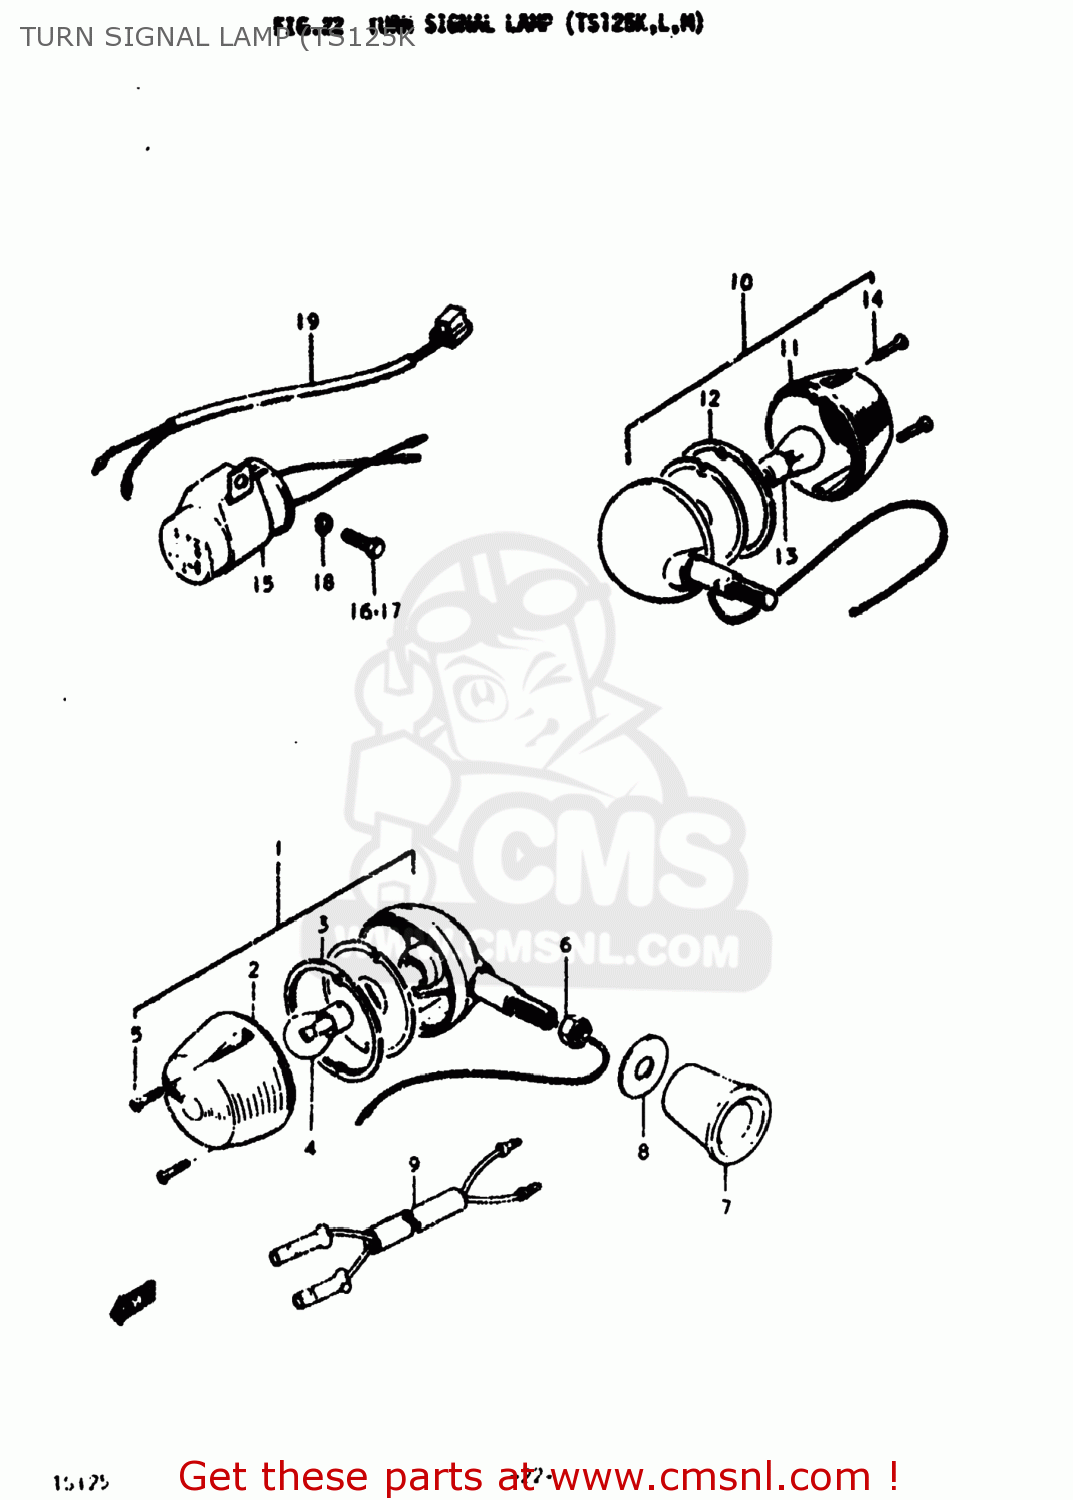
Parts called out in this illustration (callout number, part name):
1	LAMP ASSEMBLY,FRONT TURN SIGNAL
2	LENS,TURNSIGNAL
3	GASKET,TURNSIGNAL LENS (NAS)
4	BULB(6V17W,STANLEY,A4513A)
5	SCREW
6	NUT
7	COVER,FRONT TURN SIGNAL BRACKET
8	WASHER
9	WIRE,REAR TURN SIGNAL,LEFT
10	LAMP ASSEMBLY,REAR TURN SIGNAL
11	LENS,TURNSIGNAL
12	GASKET,TURNSIGNAL LENS (NAS)
13	BULB(6V17W,STANLEY,A4513A)
14	SCREW
15	RELAY,TURN SIGNAL
16	BOLT
17	BOLT
18	LOCK WASHER
19	WIRE
